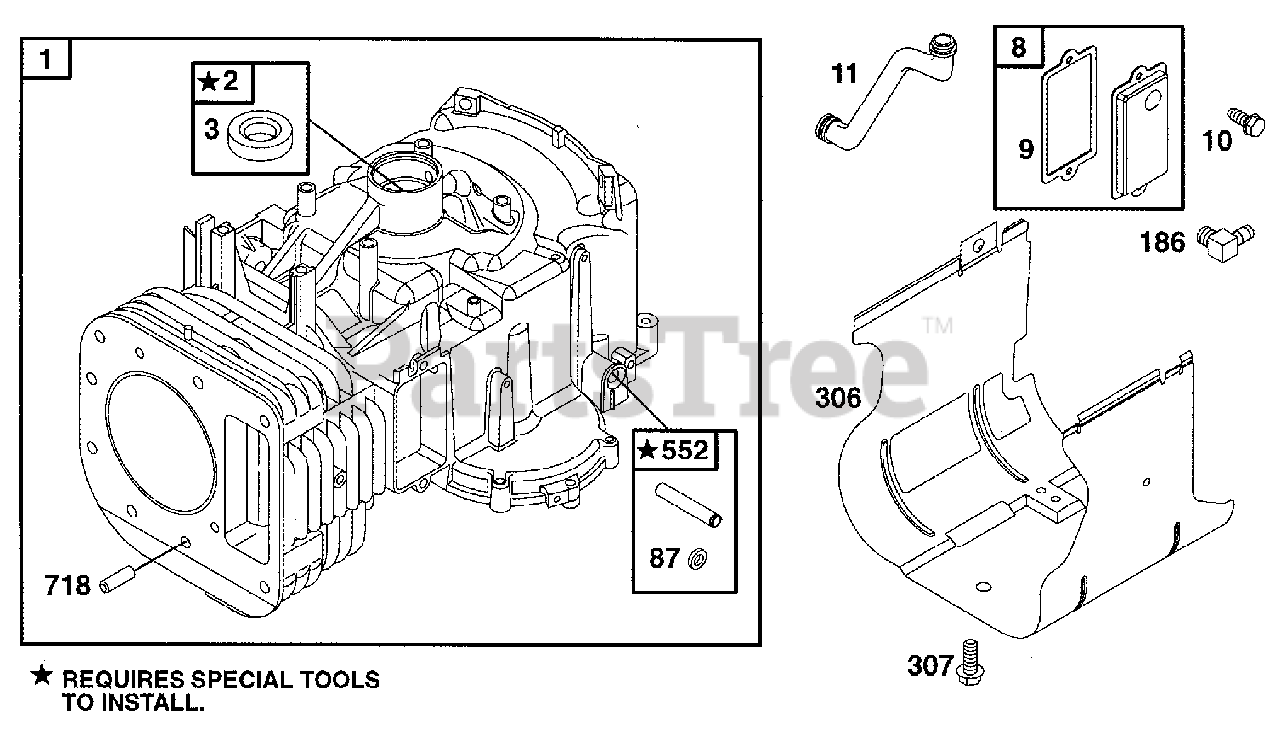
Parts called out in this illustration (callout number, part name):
1	Cylinder Assembly
2	Bushing/Seal Kit
3	Oil Seal
8	Breather Assembly
9	Breather Gasket
10	Hex Screw
11	Breather Tube
87	Governor Shaft Seal
186	Hose Connector
306	Cylinder Shield
307	Hex Screw
552	Governor Crank Bushing
718	Locating Pin
